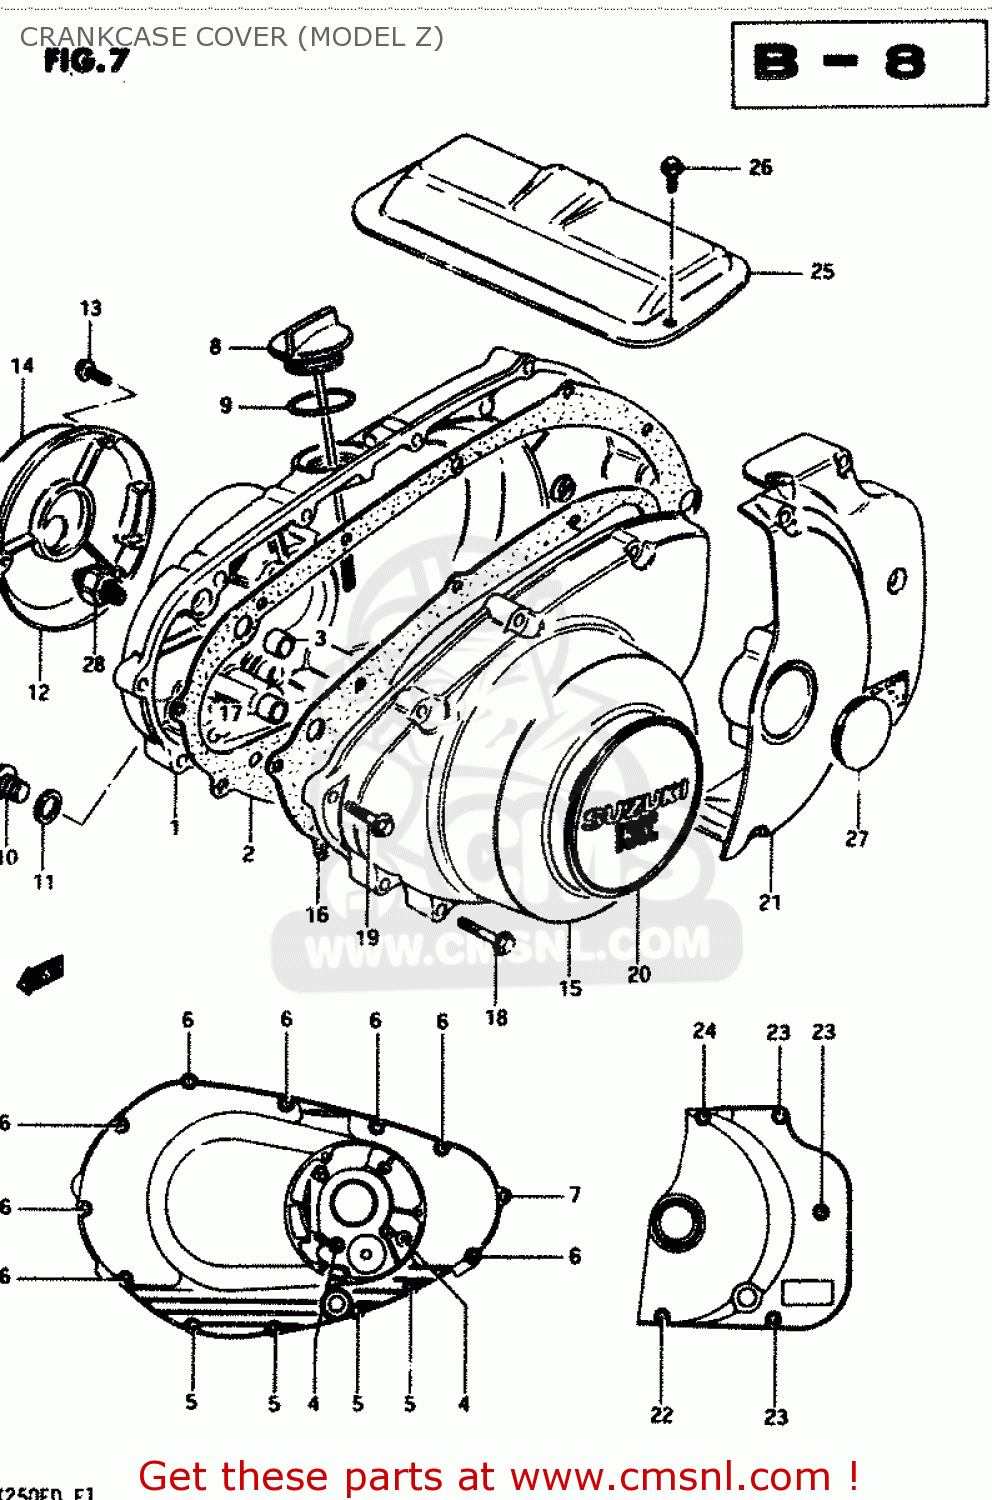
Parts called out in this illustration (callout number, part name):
1	COVER,CLUTCH
2	GASKET,CLUTCH COVER (MCA)
3	PIN
4	BOLT (6X50)
5	BOLT
6	BOLT (6X35)
7	BOLT
8	GAUGE,OIL LEVEL
9	O-RING
10	PLUG (14X12)
11	GASKET(14X19.2X2) (NAS)
12	COVER,CONTACT BREAKER
13	BOLT (5X20)
14	EMBLEM
15	COVER,MAGNETO
16	GASKET,MAGNETO COVER (MCA)
17	PIN
18	BOLT (6X30)
19	BOLT
20	EMBLEM
21	COVER,ENGINE SPROCKET
22	BOLT
23	BOLT (6X40)
24	BOLT (6X30)
25	COVER,STARTER MOTOR
26	BOLT
27	CAP(OD:36)
28	SWITCH ASSEMBLY
